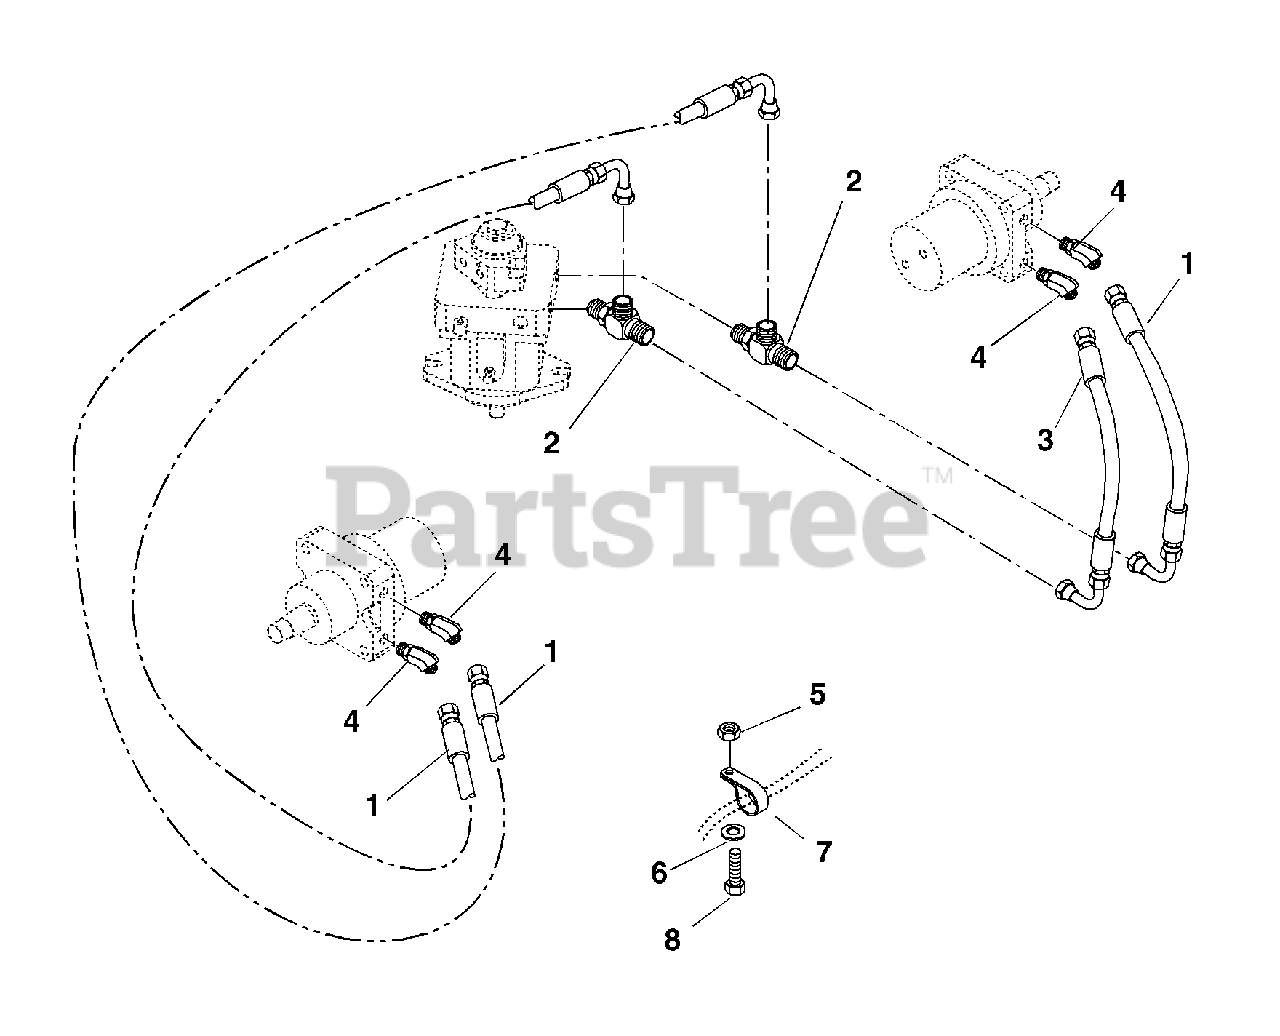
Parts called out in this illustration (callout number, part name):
1	Hose, Pump To Motor
2	Fitting, Hydraulic
3	Hose, Pump To Motor
4	Fitting, Hydraulic
5	Nut-Locking-Nylon .38-16
6	Washer-Flat-Steel .406 x .812 x .065
7	Clamp, Nylon
8	Bolt-Hex .38-16 x 1.00 Grade 5
